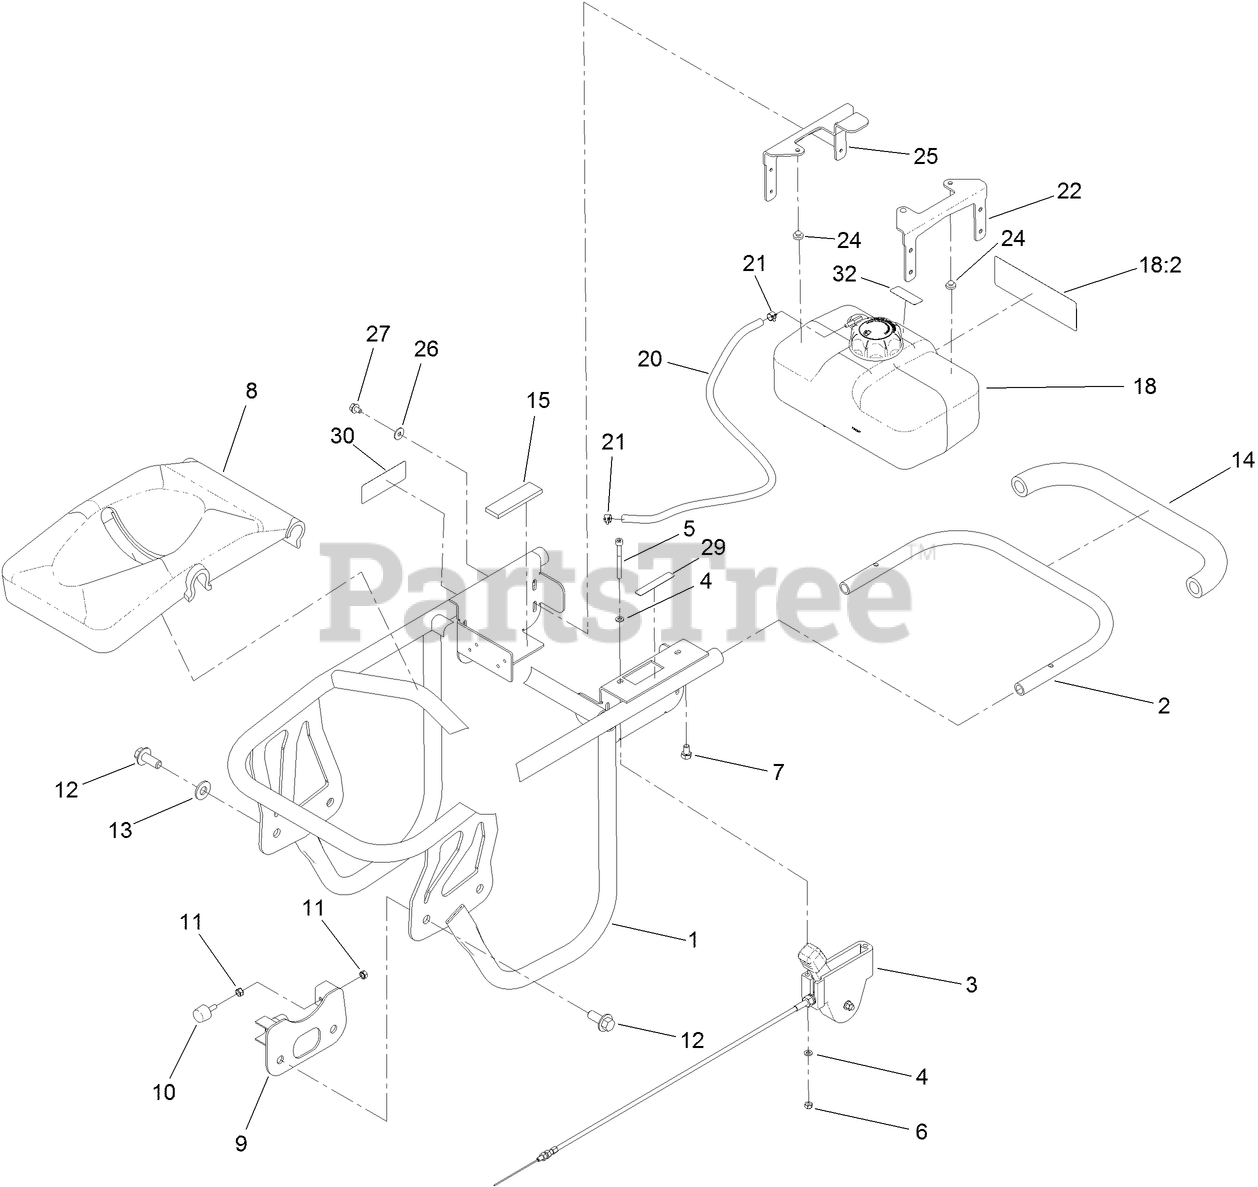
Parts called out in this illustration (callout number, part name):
1	HANDLE ASM
2	HANDLE-RAMMER
3	THROTTLE LEVER ASM
4	WASHER-FLAT
5	SCREW-HSH
6	NUT-LOCK
8	COVER-ENGINE
9	STOPPER
10	MOUNT-SHOCK
11	NUT-HEX
12	SCREW-HHF
13	WASHER
14	GRIP-CUSHION, HANDLE
15	PAD-TANK, FUEL
18	1 GALLON FUEL TANK ASM
18:2	DECAL-WARNING
20	HOSE-FUEL
21	CLAMP-HOSE
22	BRACKET-TOP, FUEL TANK
24	BUMPER-RUBBER
25	GUARD-FUEL TANK, TOP
26	WASHER-FLAT
27	SCREW-HHF
29	DECAL-THROTTLE
30	DECAL-ARRESTOR, SPARK
32	DECAL-WARNING, ETHANOL
